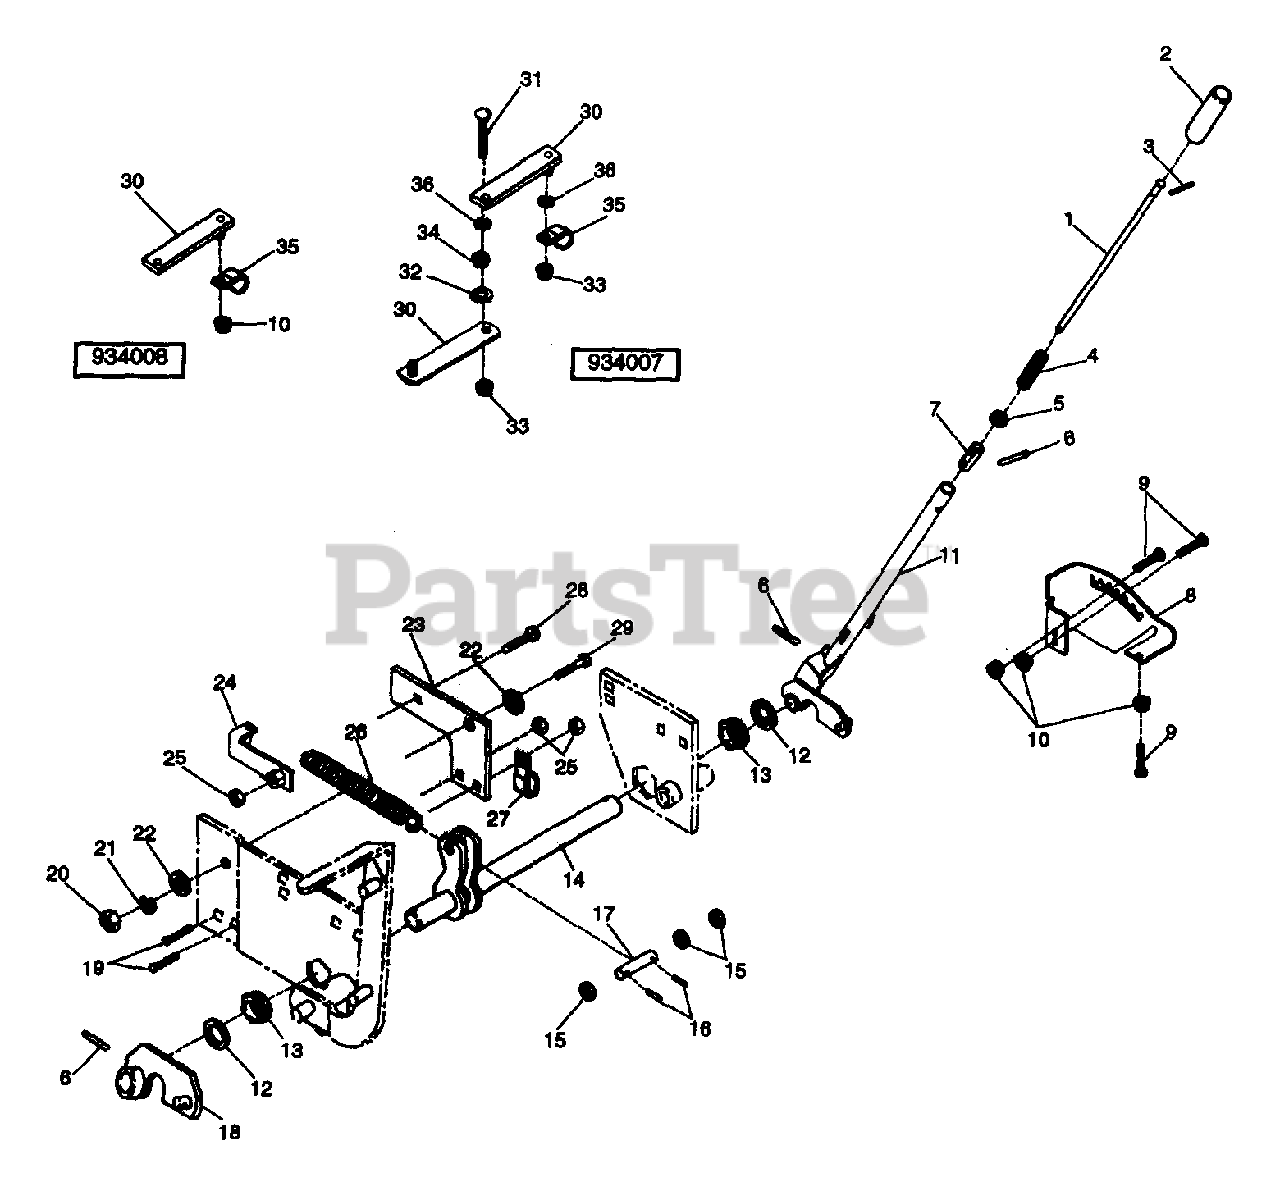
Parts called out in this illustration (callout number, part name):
2	HANDLE GRIP
3	PIN-ROLL .125X.63
4	SG-COMP .048X.59X2.06 WLD9
5	WSHR-FL-STL .458X.750X.06 PL
6	PIN-GRV .250X1.50 TP A
8	LIFT QUADRANT
9	BLT-RDHDSQNK .31-18X1.00 PL
10	NUT-FLG. .312-18 PL
11	LIFT LEVER
12	WSHR-FL-STL 1.015X1.500X.125
13	BSHG-FLG 1.000X1.25X.49X1.56HX
14	LIFT PIVOT
15	WSHR-FL-STL .520X.827X.062 YZ
16	PIN-ROLL .188X1.00
18	LIFT ARM RH
19	BLT-RDHDSQSHNK .38-16X1.00 PL
20	NUT .50-13 PL
21	WSHR-LK .500X.151 HVY PL
22	WSHR-FL-STL .511X1.441X.125 PL
25	NUT-LK-CTR .375-16 GR A PL
26	SG-TENS .188X1.50X8.5 WLD 57
27	J-CLAMP
28	BLT-RDHDSQNK .38-16X1.75 PL
29	BLT-HEX .50-13X1.25 PL GR2
30	BRACKET
31	BLT-RDHDSQNK .31-18X1.50 PL
32	WSHR-FL-STL .380X.875X.179 PL
33	NUT-LK .312-18 GR A PL
34	NUT-HEX .312-18
35	CLIP
36	WSHR-LK .312X.097 PL HVY
